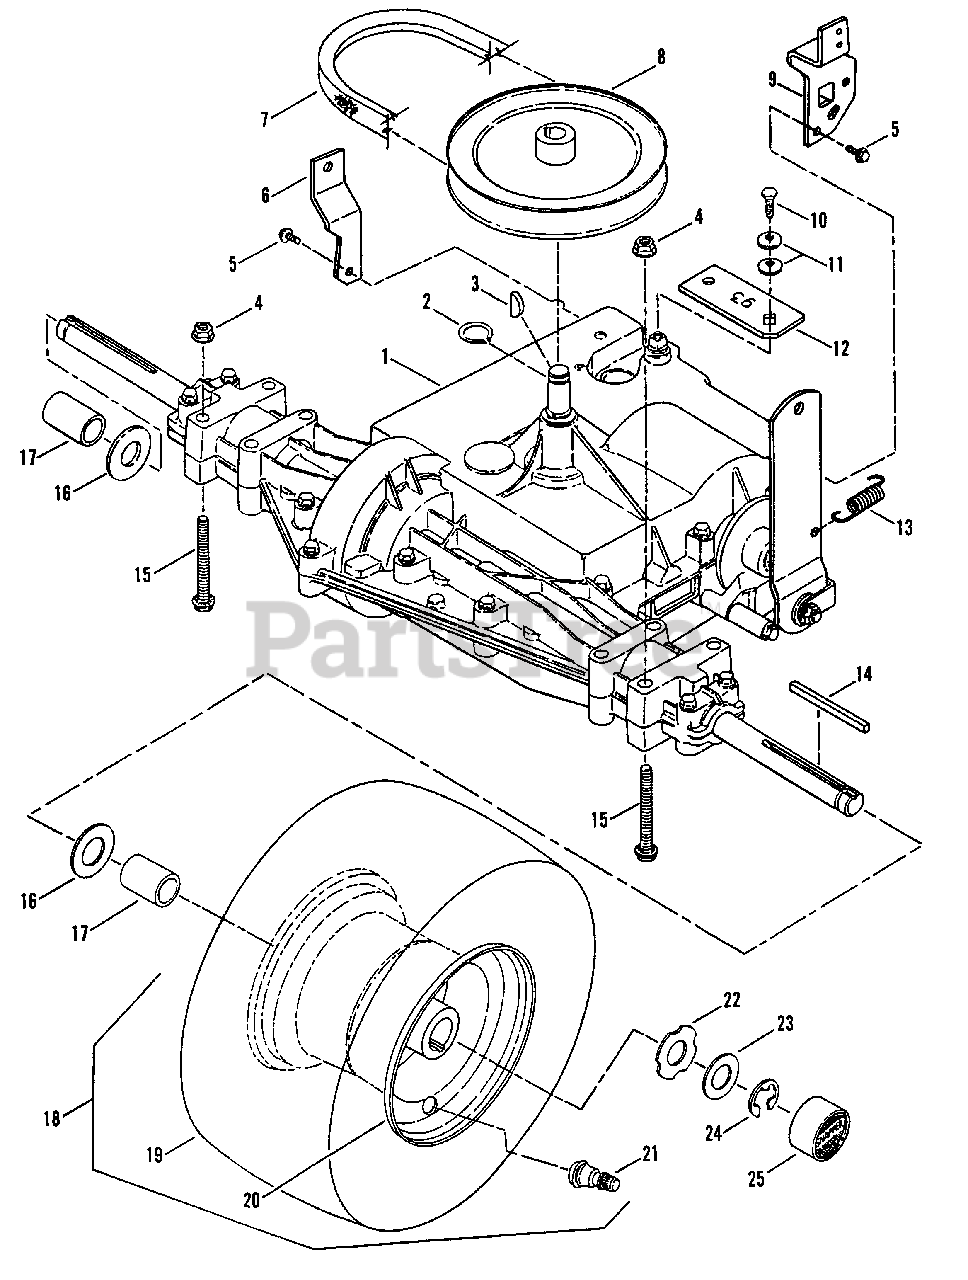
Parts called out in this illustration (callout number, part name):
1	TRANSAXLE, Gear Drive, Peerless Mod. MST205-514, 5-Speed
2	RING, Retaining
3	KEY, Woodruff, 3/16 x 3/4", No. 9
4	NUT, 5/16-18 Hex Flange Lock
5	SCREW, 5/16-18 x 5/8" Hex Washer Head, Self-Tapping
6	BRACKET, Torque
7	BELT, Traction Drive, 97.75" EL
8	PULLEY, Drive
9	BRACKET, Axle/Spool
10	BOLT, 1/4-28 x 5/8" Hex Head
11	WASHER, Bellville
12	ARM, Shift Link Lever
13	SPRING, Brake Return
14	KEY, Square, 3/16 x 3/16 x 2-1/2"
15	BOLT, 5/16-18 x 2-1/4" Hex Flange Lock
16	WASHER, Flat
18	ASSEMBLY, Rear Tire & Rim
19	TIRE, 18 x 7.50
20	RIM, 8 x 5.375
21	VALVE, Air (Snap-in)
22	WASHER, Hub-Cap Retaining
23	WASHER, Flat, .07 x .77 I.D. x 1.31 O.D.
24	RING, Retaining
25	HUB-CAP
